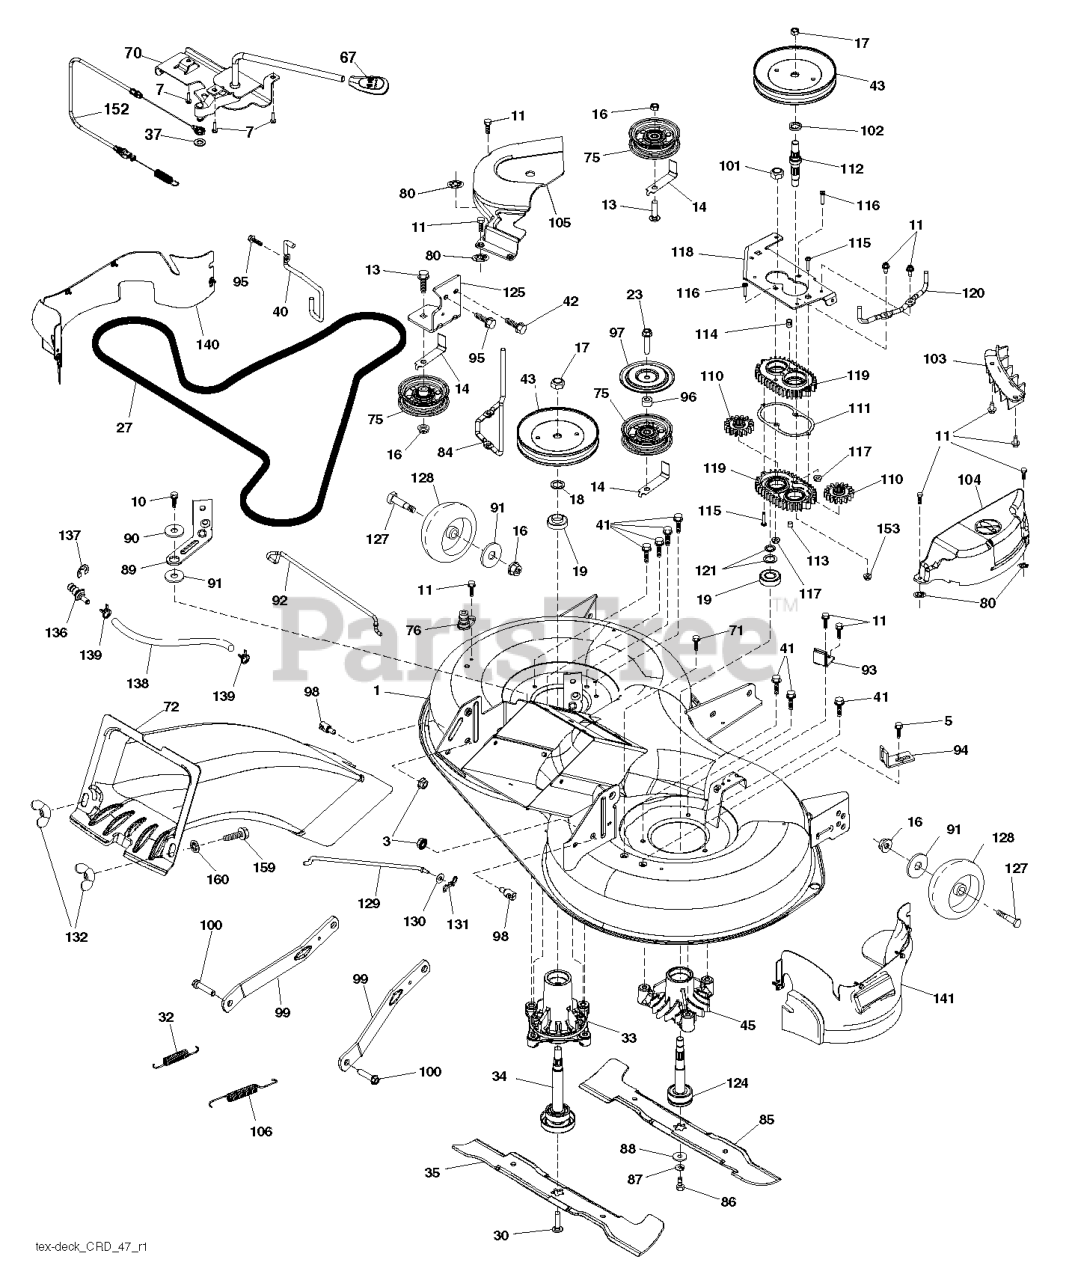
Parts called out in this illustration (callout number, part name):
1	DECK.WELDMENT.97.TEX.498
3	NUT LOCK HEX FLANGE 5/16-18
5	BOLT.5/16HEX.WHS.HD
7	SCREW.#10 X 0.750.BOS
10	SCREW 3/8-16X1
11	SCREW.1/4-20X5/8
13	BOLT.3/8-16X1.50
14	KEEPER, BELT IDLER
16	NUT LOCK FLG 3/8-16 UNC
17	NUT.FLANGE.LOCK.TOP
18	WASHER.SPACER.MANDREL
19	BEARING.MANDREL.TOP.EXTENDED
23	SCREW LT
27	BELT V-BELT DRIVE
30	SCREW.SEMS.7/16-20X1.HEX.HEAD
32	SPRING RETURN
33	RP.HOUSING.MANDREL.4PT.
34	SHAFT ASM.MNDRL.N/GREASEABLE
35	BLADE.3N1.LH.CRD.97
37	WASHER
40	KEEPER BELT ENGINE LH
41	BOLT.HEX.WASHR.HED.313-18X1.19
42	SCREW
43	PULLEY.MANDREL.5.438.PD
45	HOUSING.MANDREL.44/46" VENT
67	HANDLE.CLUTCH.CABLE.LT
70	CLUTCH.ASM.MANUAL.LT.PRED
71	SCREW 3/8-16X1/2
72	CHUTE.TEX.CRD.GEN I.97 UPPER
75	FLAT IDLER PULLEY
76	1/2" BARB.DECK.WASHOUT.PORT
80	PALNUT 1/4
84	KEEPER.BELT.MANDREL.PULLEY
85	BLADE.3N1.RH.CRD.97
86	BOLT.3/8-24X1.25GR8. LHTHRD
87	SLW 3/8 STD
88	WASHER.BLADE
89	ARM.BRAKE.97.LH
90	SPACER.RETAINER
91	WASHER
92	ROD ROD BRAKE
93	ARM.BRAKE.97.RH
94	BRKT.CLUTCH.CABLE
95	SCREW, 3/8-16X3/4
96	SPACER
97	PROTECTOR
98	STUD.FASTNER.W/ANTI-ROTATE
99	ARM.SUSPENSION.MOWER.R
100	BOLT.SHOULDER
101	NUT.CROWNLOCK.9/16 -18.UNC
102	SPACER BEARING
103	GUARD GUARD FRONT VENT
104	97.CRD.RH.MANDREL.COVER
105	MANDREL MANDREL COVER LH
106	SPRING.BRAKE.RETURN.38"
110	CRD.SPUR.GEAR
111	GASKET GASKET GEARCASE
112	SHAFT SHAFT. CRD GEARCASE ADAP
113	PLUG PLUG OIL
114	VENT.BREATHER.1/8 NPT
115	SCREW
116	BOLT.CARIGE.SS.1/4-20X1.75GR5
117	NUT T
118	ARM ARM CLUTCHING
119	GEARCASE GEARCASE SUBASM
120	BRACKET KEEPER BELT RH
121	WASHER WASHER
124	MANDREL SHAFT NON/GREASE
125	BRACKET
127	BOLT.SHOULDER.3/8-16X3-5/8.
128	WHEEL.GAUGE.RALLY
129	ROD.ANTI.SWAY.48/54"K4
130	WASHER
131	PIN.COTTER.5/16.BOW TI
132	KNOB.HANDLE.3/8.TRI-POINT.BLAC
136	PLUG WASHOUT PORT HOOKUP
138	HOSE.3/8ID.BULK.12"
139	HOSE.3/8.CLAMP (2 2)
140	GUARD.ASSEMBLY.97.LH.FRENCH
141	GUARD.ASSEMBLY.97.RH.FRENCH
152	CABLE CABLE CLUTCH MANUAL W/S
153	NUT HEXAGON 9/16-18 G2 ZPB LOC
